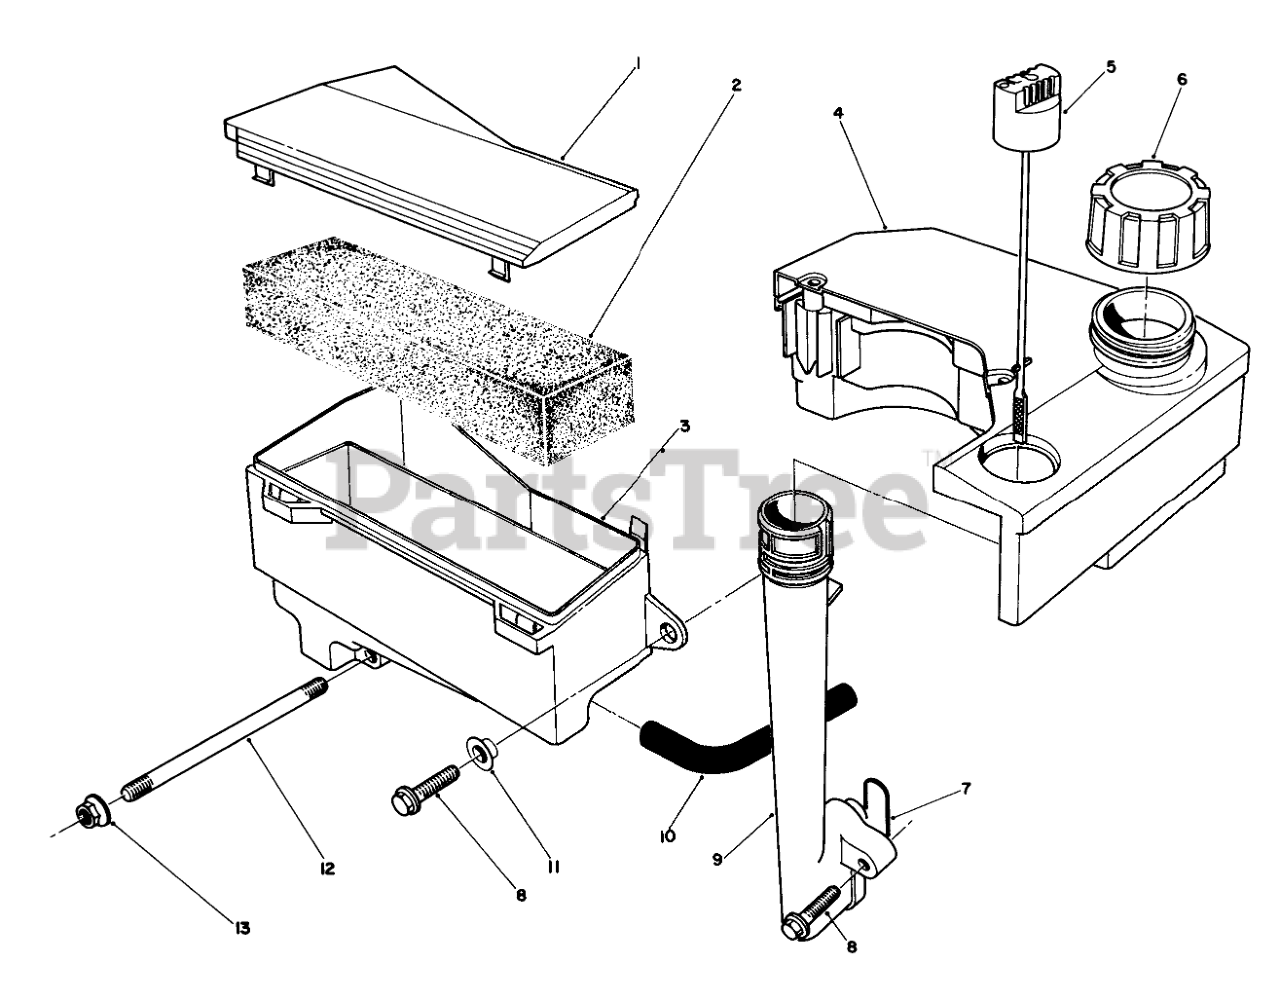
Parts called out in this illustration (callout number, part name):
1	AIR CLEANER CAP
3	Air Cleaner Assembly (Incl. Ref. #1)
4	TANK ASM
5	Dipstick
6	GAS CAP ASM
7	O-RING
11	SPACER
12	Stud-Carburetor
